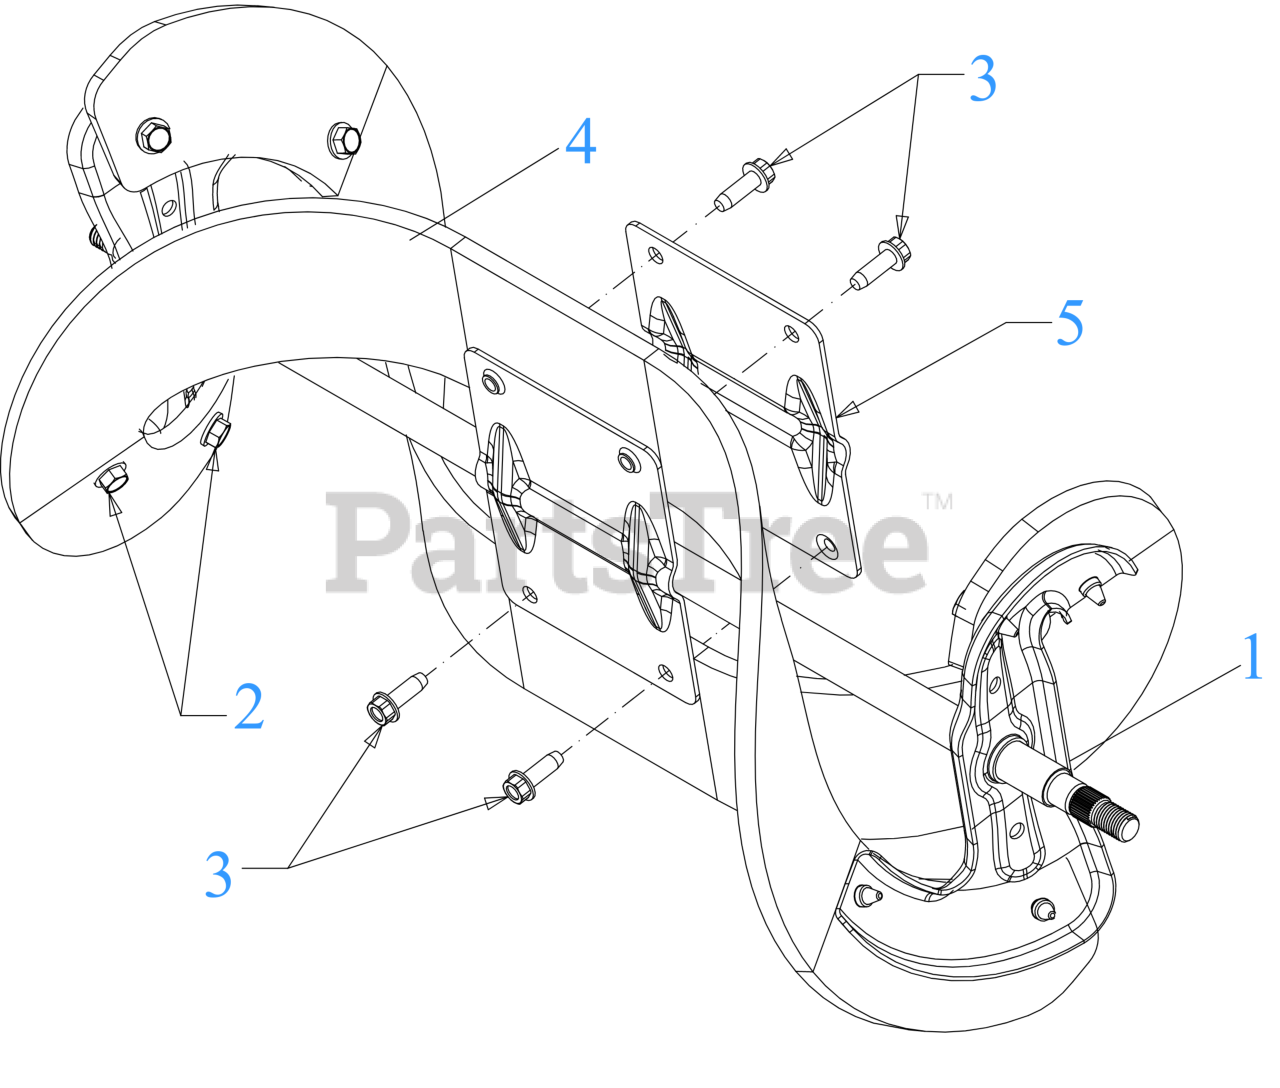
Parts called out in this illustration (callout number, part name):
2	SCREW 1/4-14 x .75
3	SCREW 1/4-20 x .750
4	AUGER RUBBER PADDLE
5	AUGER CENTER BRACKET
